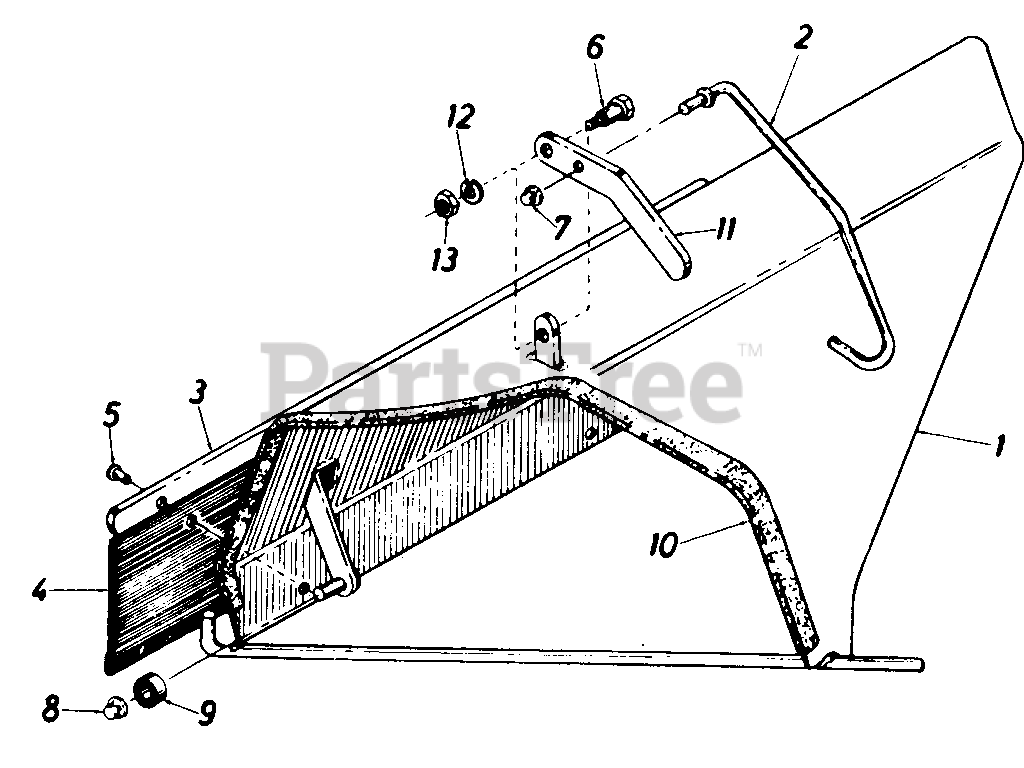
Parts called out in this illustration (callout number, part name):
1	Deflector Ass'y.
2	Hook Ass'y.
3	RetainingStrip
5	Rivet
6	Shld. Bolt .375" Dia. x . 171 Lg.
7	Palnut 1/4" Rod
8	Palnut 3/8" Rod
9	Roller
10	Moulding
11	Latch Arm
12	L-Wash. 1/4" I.D.
13	Hex Nut 1/4-20 Thd.*
